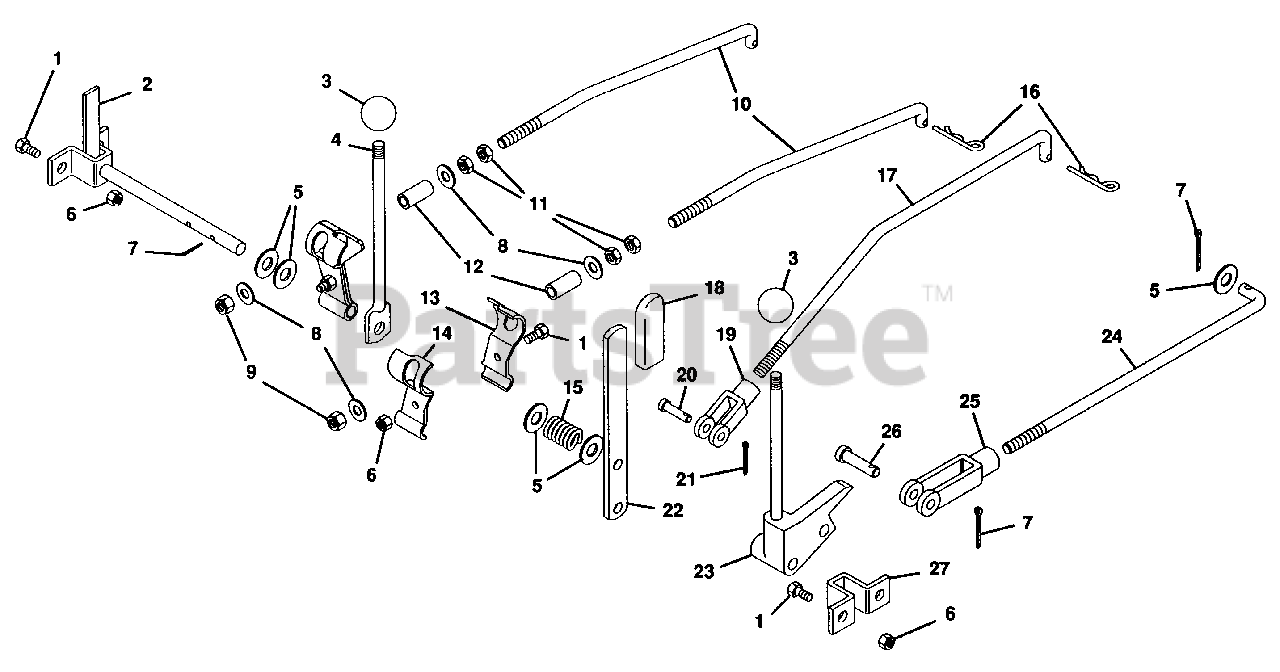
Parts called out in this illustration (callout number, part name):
1	BOLT, HEX 5/16-18X.75
2	WELDMENT, CROSS SHAFT
3	KNOB, CONTROL
4	LEVER, SHIFT
5	WASHER, FLAT .531X1.06X.095
6	NUT, LOCK 5/16-18
7	PIN, COTTER .12X1.0
8	WASHER, FLAT .438X1.00X.083
9	NUT, LOCK 3/8-16
10	ROD, SHIFT
11	NUT, JAM 3/8-16
12	BUSHING, .400X.500X1.65
13	ARM, SHIFTER R.H.
14	ARM, SHIFTER L.H.
15	SPRING, COMPRESSION
16	PIN, COTTER HAIR
17	ROD, 2-SPEED
18	GRIP, HANDLE
19	CLEVIS, 3/8-24 ADJUSTABLE
20	PIN, CLEVIS .375X.948
21	PIN, COTTER .09X.75
22	LEVER, HI-LO SHIFT
23	ASSEMBLY, PTO CONTROL
24	ROD, PTO
25	YOKE, 1/2-20 ADJUSTABLE
26	PIN, CLEVIS .500X1.213
27	BRACKET, CROSS SHAFT
